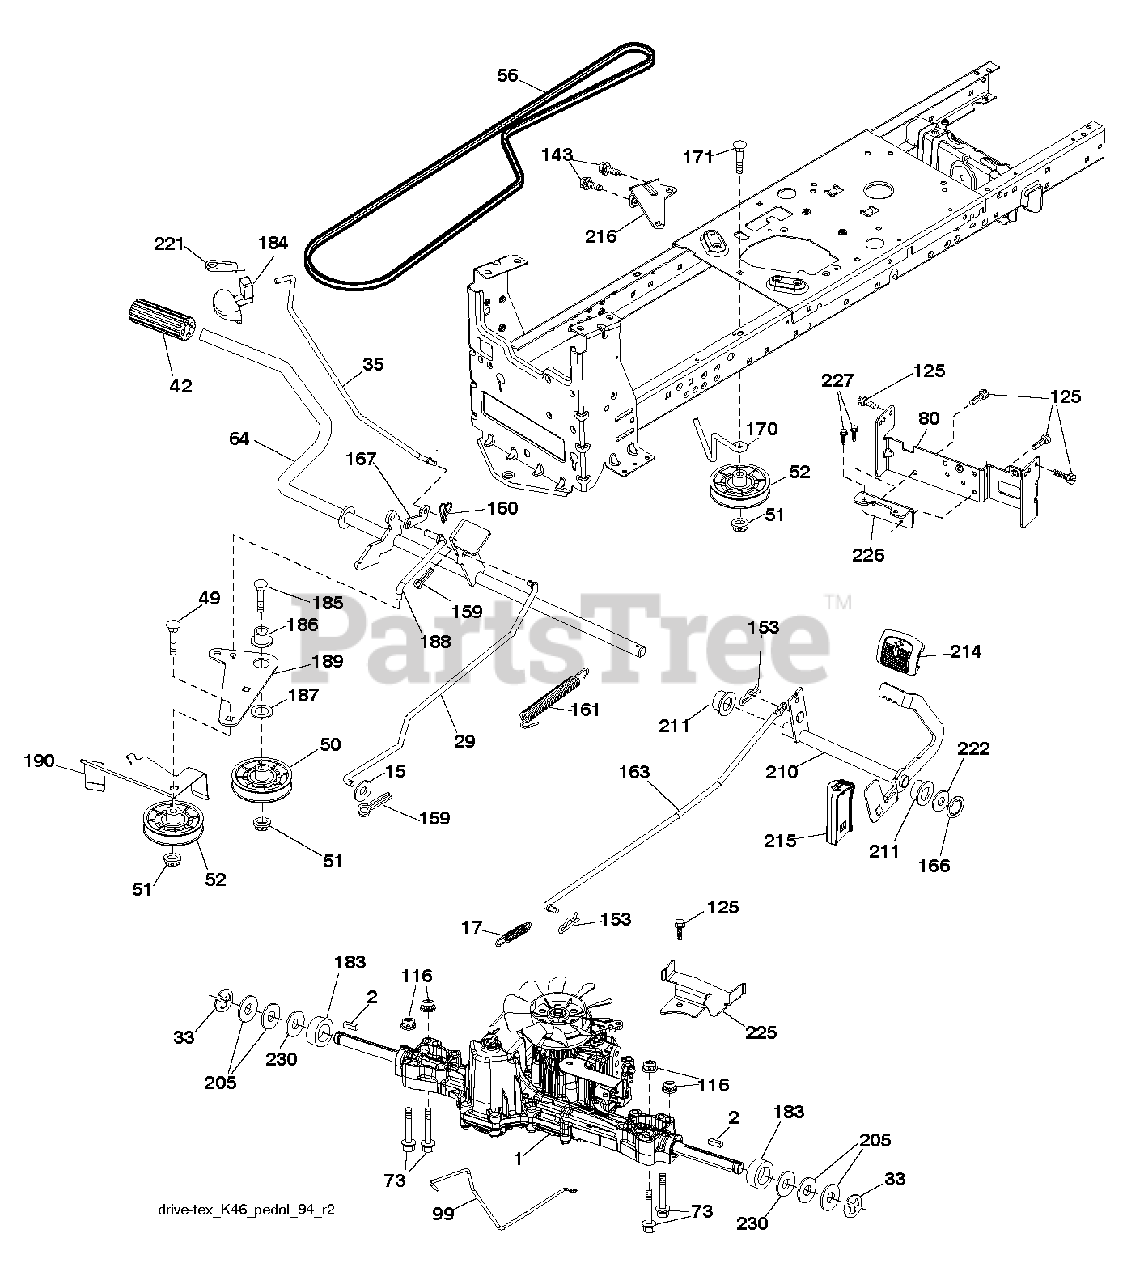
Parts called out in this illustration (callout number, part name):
2	SQUARE KEY
15	WASHER
17	SPRING, BREAK
29	ROD.BRAKE.K46
33	E-RING LT
42	PEDAL COVER T
50	IDLER.FLAT.910.OFFSET
52	IDLER.V-GROOVE.910.OFFSET
64	SHAFT.ASM.PEDAL.BRK.CN
99	ROD.SPRING.BYPASS.K46.LT.Z
116	NUT LOCK HEX FLANGE 5/16-18
125	SCREW
143	SCREW LT
159	COTTER PIN
160	RETAINER CLIP
161	SPRING, RETURN LT
166	NUT.PUSH.625
167	LATCH BRAKE PARKING
170	KEEPER.V-IDLER.CENTER.
183	SPACER AXLE
186	SPACER.RETAINER
188	LINK.CLUTCH.GROUND DRI
189	BELLCRANK.GRDDRIVE.NST
190	KEEPER.BELLCRANK.DRIVE
210	ROCKER.ASM.PEDAL.CONTR
211	BEARING RER
214	PAD PEDAL FORWARD
215	PEDAL.REVERSE.TEX.GT.4
216	BRKT.PULLEY.IDLER.WTEX
221	RETAINER.SPRING.CLIP.H
222	WASHER 21/32 X 1-1/4 X 10 GA.
225	KEEPER.BELT.TRANSAXLE.
226	BRACKET MOUNT TORQUE
